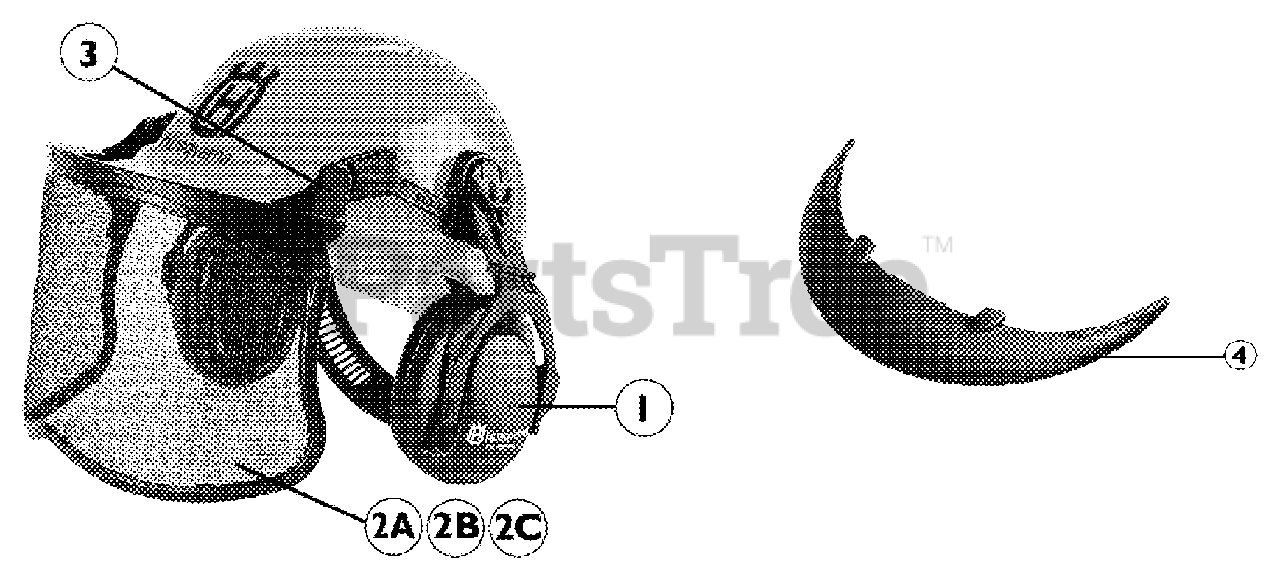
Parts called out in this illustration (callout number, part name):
1	Hearing Protector set
1	Hygiene set
2A	Mesh visor, metal
2B	Mesh visor, nylon
2C	Mesh visor, Plexiglass
3	Visor holder with attachments
4	Helmet brim/visor shield - clip on
